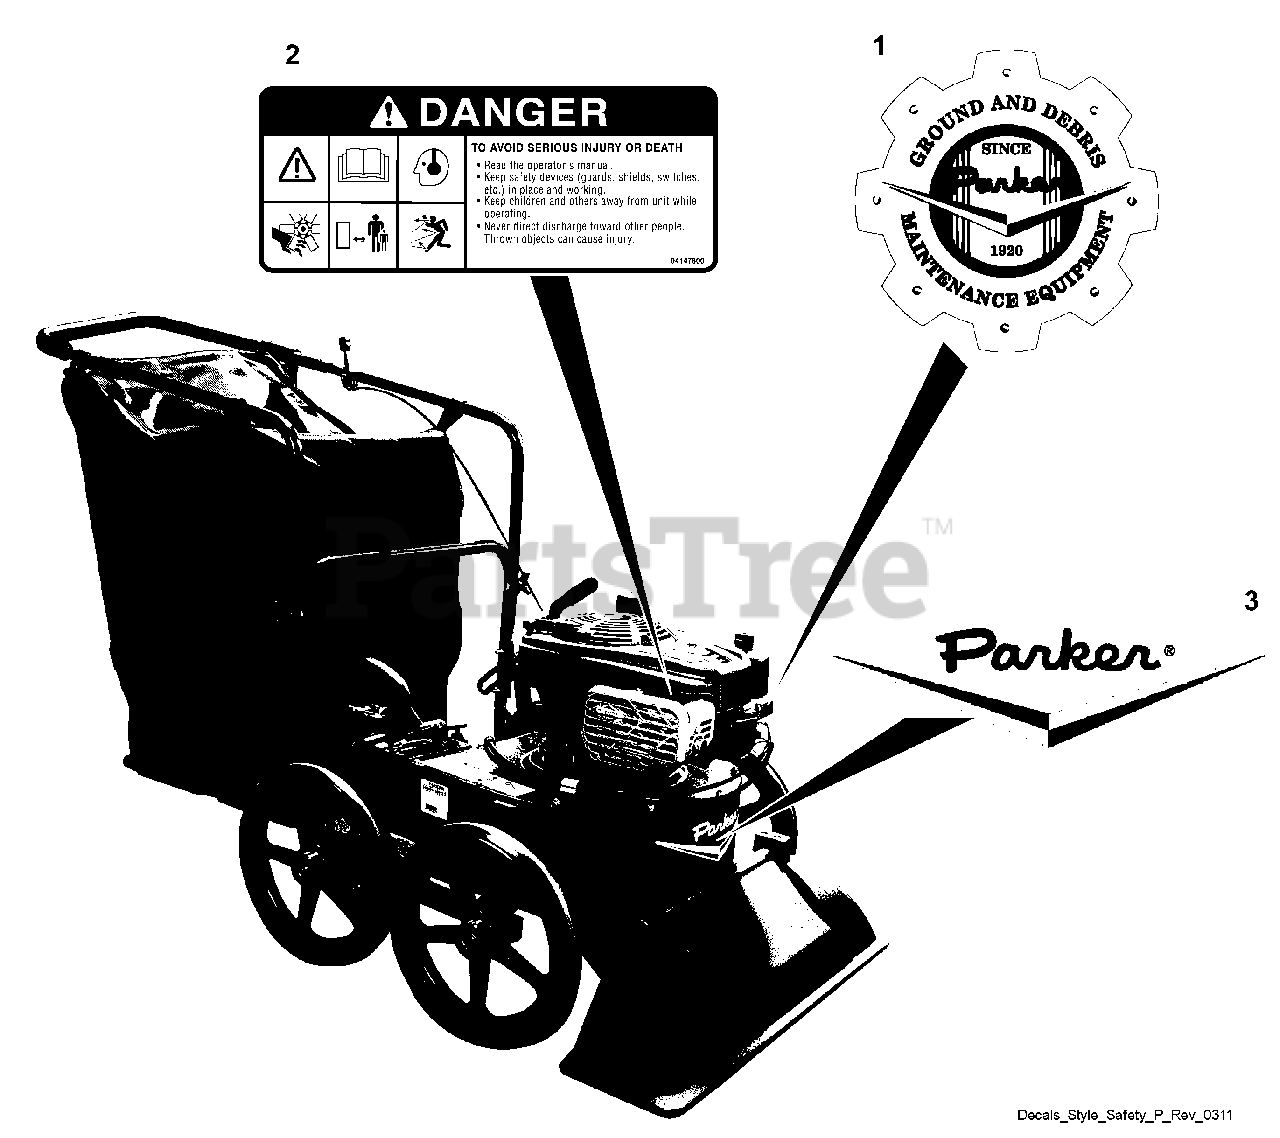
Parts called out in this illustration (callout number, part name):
1	Decal, Parker Heritage, Small
2	Decal, Danger Read Manual
3	Decal, Parker Logo
